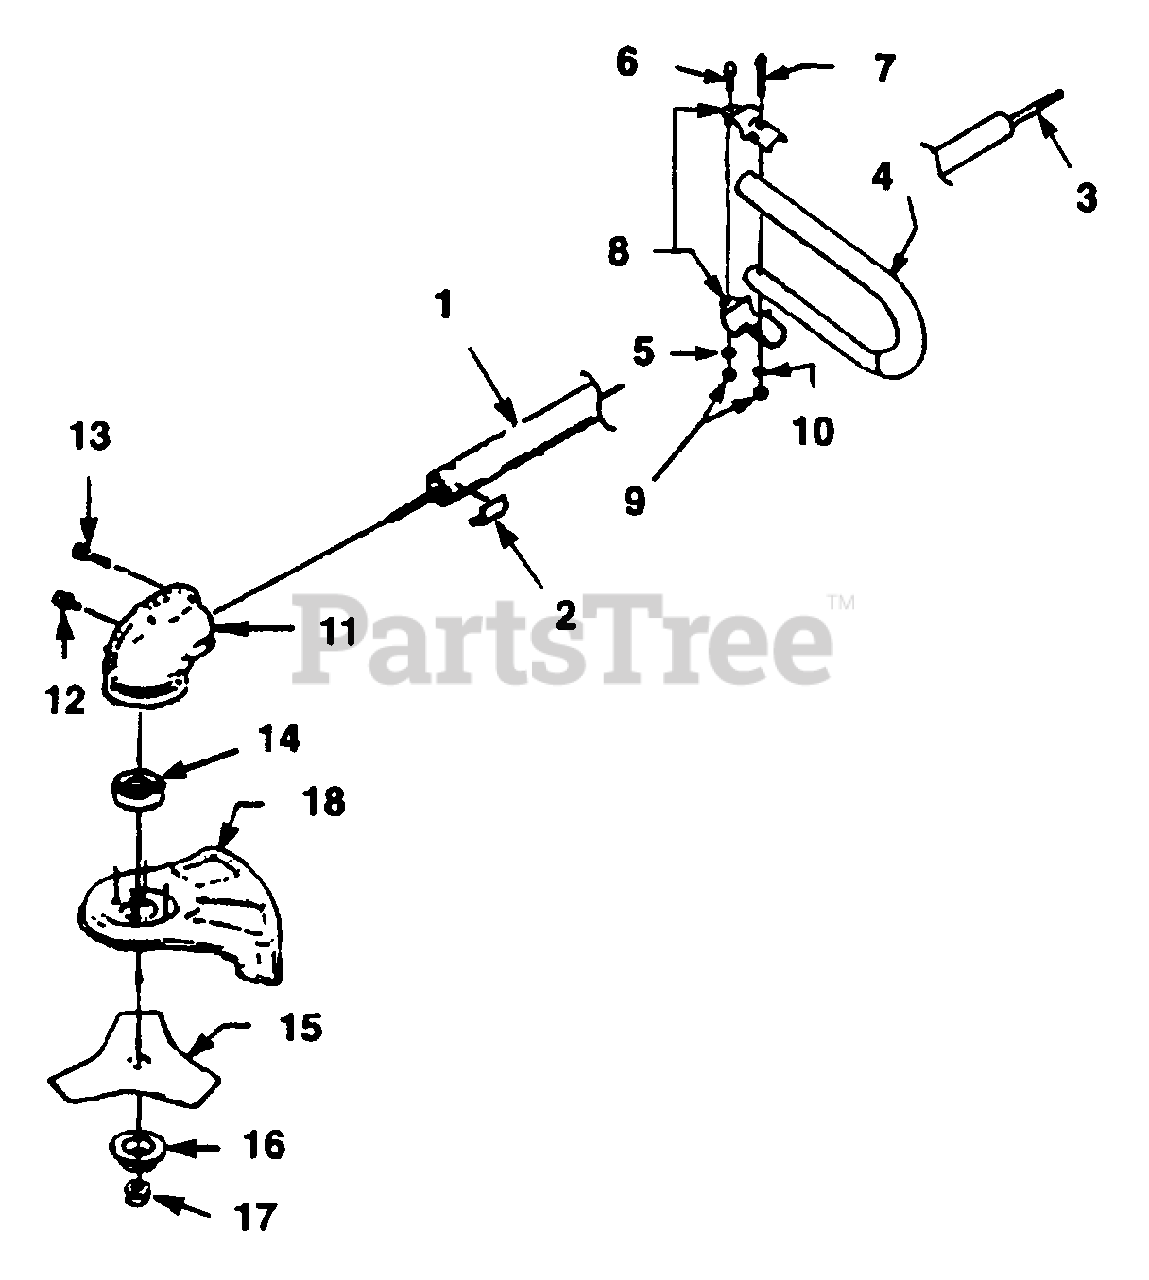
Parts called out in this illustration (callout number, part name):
1	DRIVE SHAFT HOUSING
2	DECAL - Warning
3	SHAFT - Flexible
4	FRONT HANDLE ("J")
5	WASHER - Flat
6	SCREW - Hex Hd. (1/4-20 X 1/2")
7	SCREW - Hex Hd. (1/4-20 X 1")
8	CLAMP - Handle Bar
9	NUT - Hex (1/4-20)
10	WASHER (1/4")
11	GEAR HEAD
12	SCREW - Hex Hd. (10-24 X 1/2")
13	SCREW - Hex Hd. (10-24 X 5/8")
14	WASHER - Flanged
15	BLADE - Tri-Arc (8")
16	WASHER - Cupped
17	NUT - Hex Locking (R.H.)
18	BLADE GUARD
